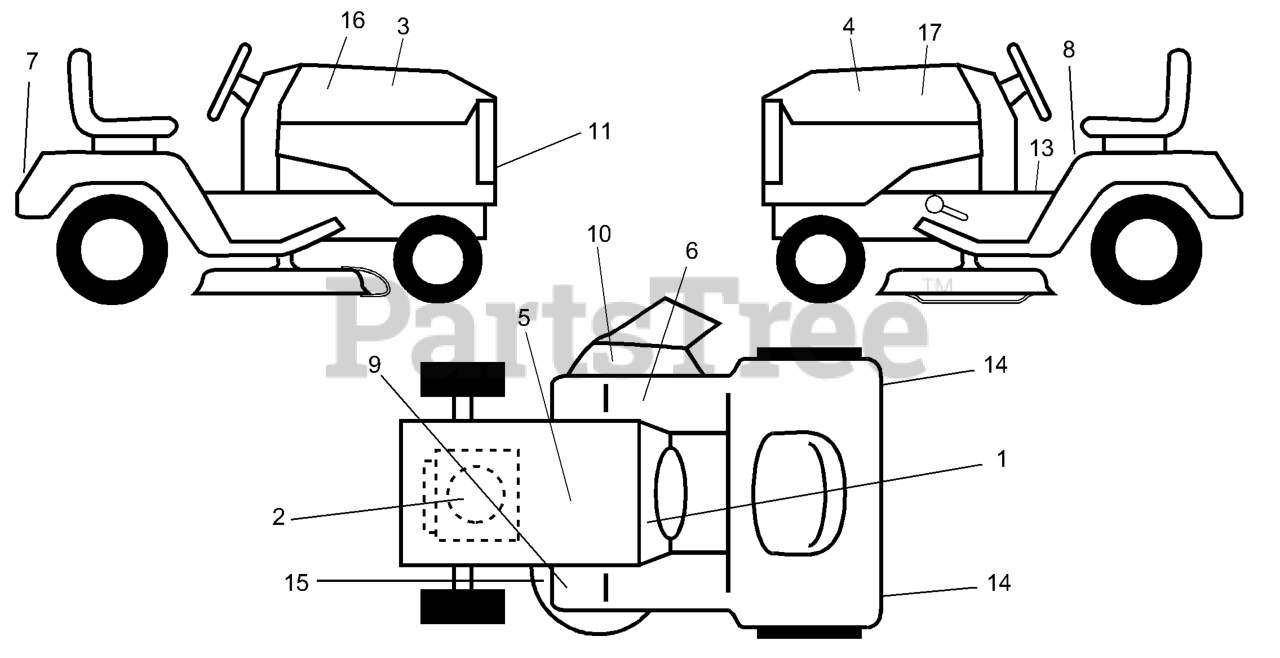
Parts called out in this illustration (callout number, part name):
2	DECAL ENGINE HP
3	DECAL-HOOD R.H.
4	DECAL-HOOD L.H.
5	DECAL BTRY SYMBOLS
7	DECAL FENDER NLA
8	DECAL CAUTION
10	DECAL WARNING (ENGLISH/FRENCH)
11	DECAL GRILL HUSQ NLA
13	DECAL PARK BRAKE
14	REFLECTOR-TAIL YT
15	DECAL V-BELT SCHEMATIC
16	HOOD DECAL
17	HOOD DECAL
